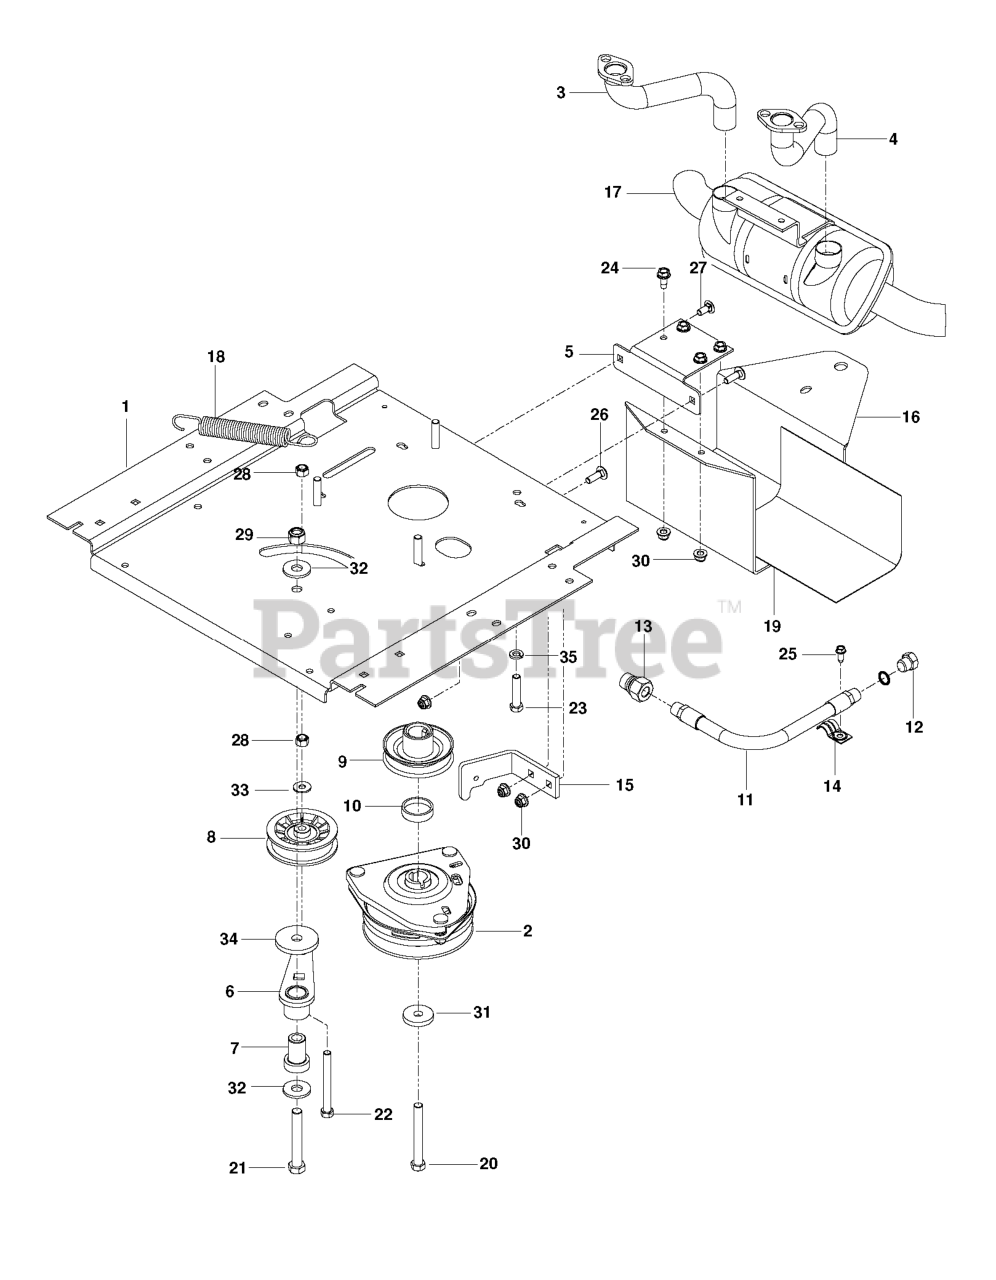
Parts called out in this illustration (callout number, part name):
1	ENGINE PLATE RZ
2	CLUTCH.ELECTRIC.LT.48"*
3	EXHAUST PIPE ASM DUAL KAW RT
4	EXHAUST PIPE ASM DYAL KAW LT
5	BRACKET, MUFFLER, BLACK
6	ARM IDLER
7	IDLER SPINDLE
8	PULLEY, IDLER RAKE & ZTR
9	PULLEY, ENGINE
10	SPACER, HUB PULLEY
11	HOSE.ASSEMBLY.OIL.DRAIN
12	PLUG OIL DRAIN
13	ADAPTER, OIL DRAIN
15	CLUTCH STOP OGR BLK
16	GUARD.MUFFLER.BLACK
17	MUFFLER OUTLET DUAL RZ
18	SPRING, DECK DRIVE
19	HEAT SHIELD
20	CLUTCH BOLT7/16-20X2.5 GR524HR
21	HCS 1/2-13 X 3-1/4 GD 5 ZD
22	HCS 3/8-16X3-1/2 TAPBLT GR5 ZD
23	BOLT, HCS 3/8-16X1-3/4
24	SCREW.THDROL.5/16-18X3/4.TTY
25	SCREW 1/4 X 5/8
27	RP BOLT 5/16-18 X3/4 ZN/YEL GR
28	NUT 3/8-16 NYLOC
29	NUT.LK.W/WSH.1/2.
30	5/16-18 NYLOC FLANGE NUT
32	WASHER.9/16 X 1 3/8 X 12 GA.
33	WASHER.5/16.FLAT.STE.STD.
34	HEAVY WASHER
35	LOCKWASHER
